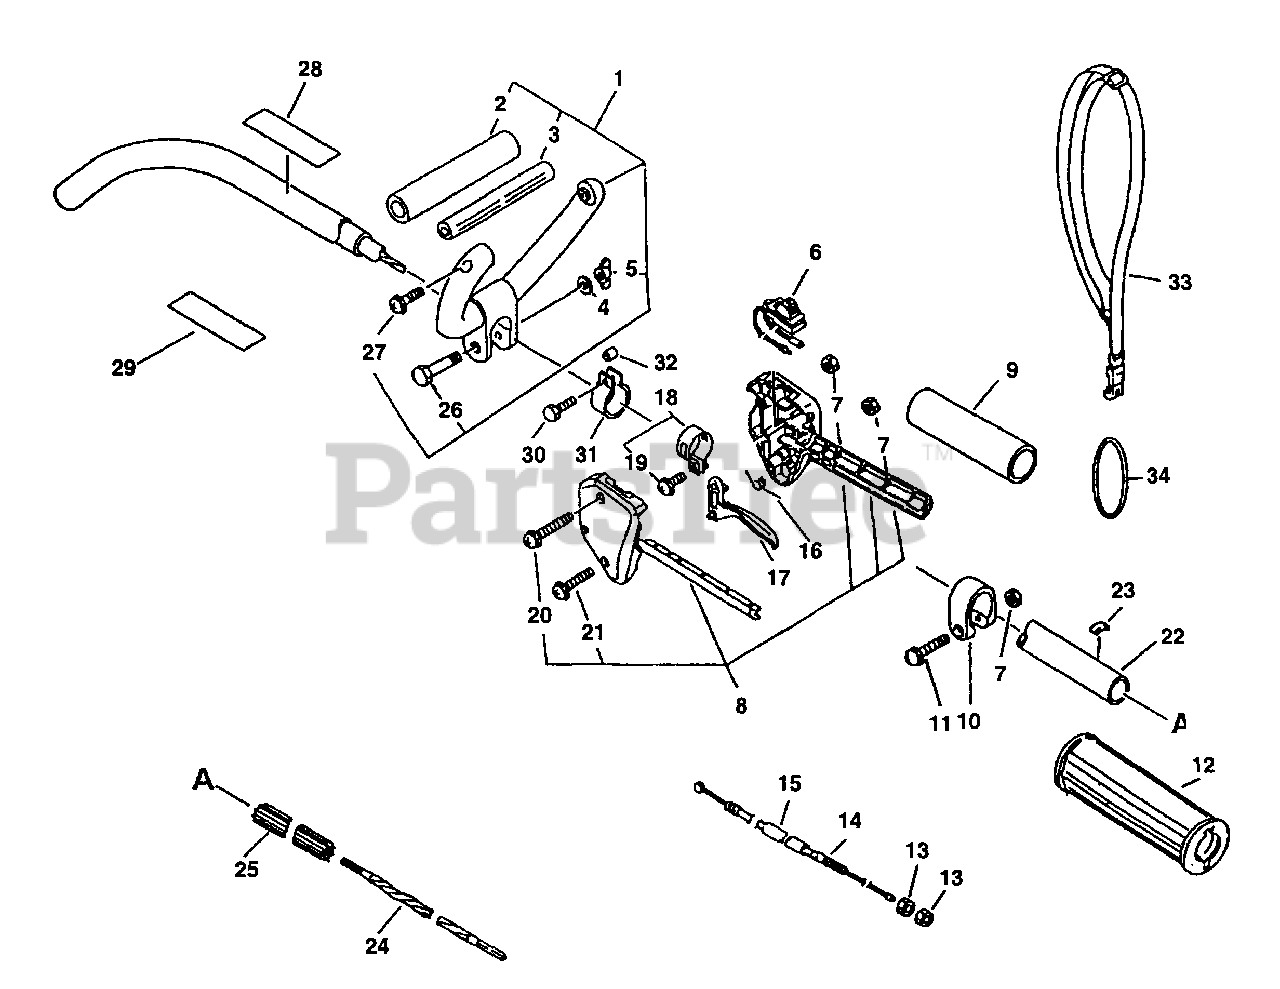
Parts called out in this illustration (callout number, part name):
1	LOOP HANDLE ASSY
2	GRIP, HANDLE
4	WASHER - 6
5	WINGNUT - 6
6	IGNITION SWITCH ASSY
8	THROTTLE BRACKET SET
9	GRIP, HANDLE - REAR
11	SCREW - 5X28
12	GRIP, HANDLE
14	CABLE, THROTTLE
15	TUBE - VINYL
16	SPRING, TRIGGER
17	TRIGGER, THROTTLE
18	CLAMP KIT
19	SCREW - 5X14
20	SCREW - 5X35
21	SCREW - 5X25
22	MAIN PIPE ASSY
23	LABEL - ALIGNMENT
24	DRIVESHAFT - FLEXIBLE
25	LINER - FLEXIBLE
26	BOLT - 6X40
27	SCREW - 5X30
28	LABEL - CAUTION
29	LABEL - CAUTION
30	BOLT - 5X18
31	HOOK
32	SPACER
33	SHOULDER STRAP ASSY
34	RING
